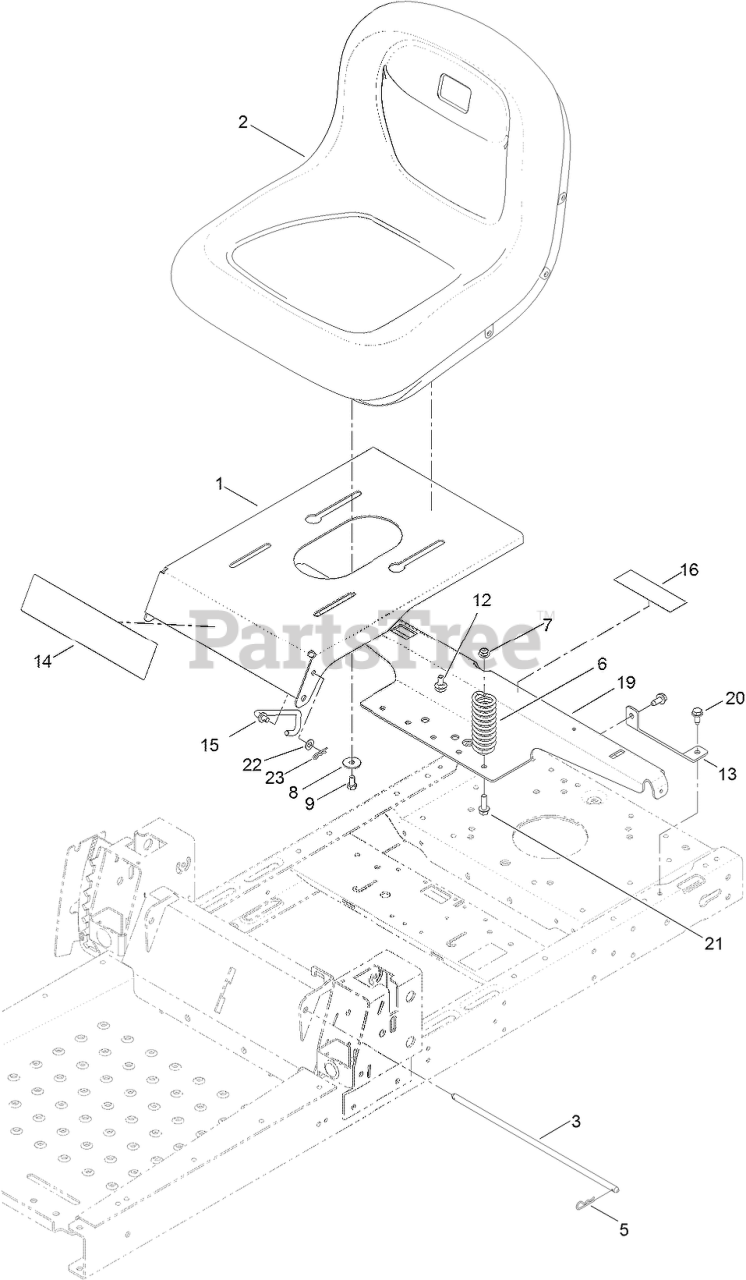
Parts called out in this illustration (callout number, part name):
1	PAN-SEAT
2	SEAT-15 INCH
3	ROD-PIVOT, NARROW
5	PIN-COTTER
6	SPRING-COMPRESSION
7	NUT-HF, NI
8	WASHER-PIVOT
9	SCREW-HH
12	BOLT-SHOULDER
13	SUPPORT-TANK, REAR
14	DECAL-TIMECUTTER
15	STOP-SEAT
16	DECAL-SERVICE, CE
19	SUPPORT-POD
20	SCREW-HWHTF
21	SCREW-HHF
22	WASHER-PLAIN
23	PIN-COTTER
